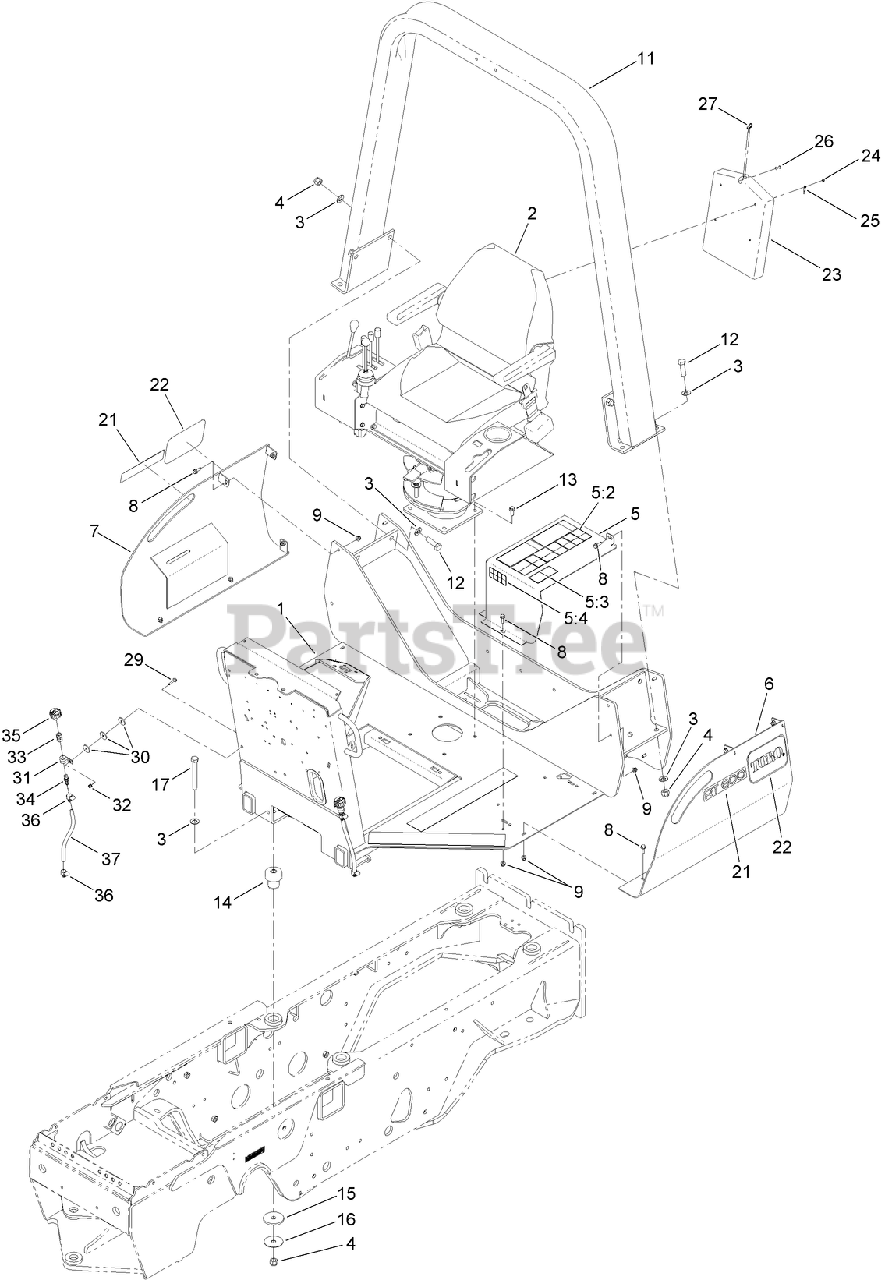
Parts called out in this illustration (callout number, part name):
1	PLATFORM-OPERATOR
2	SEAT ASM
3	WASHER-FLAT
4	NUT-HEX
5	BATTERY COVER ASM
5:2	DECAL-SAFETY
5:3	DECAL-SAFETY
5:4	DECAL-WARNING, BATTERY
6	FENDER-LH
7	FENDER-RH
8	SCREW-HHF
9	NUT-LOCK, HHF
11	ROPS ASM
12	SCREW-HH
13	SCREW-HHF
14	MOUNT-REAR
15	WASHER-SNUBBING
16	WASHER
17	SCREW-HH
22	DECAL
23	HOLDER-MANUAL, OPERATOR
24	RIVET-POP
25	LANYARD
26	POST-MANUAL
27	STRAP-TIE, NYLON
29	SCREW-HHF
30	Washer-Flat
31	CLAMP-R
32	NUT-FLANGE, NI
33	COUPLING-PIPE (NPTF)
34	FITTING-STRAIGHT
35	BREATHER
36	CLAMP-HOSE, WORM DRIVE
37	HOSE-BREATHER
